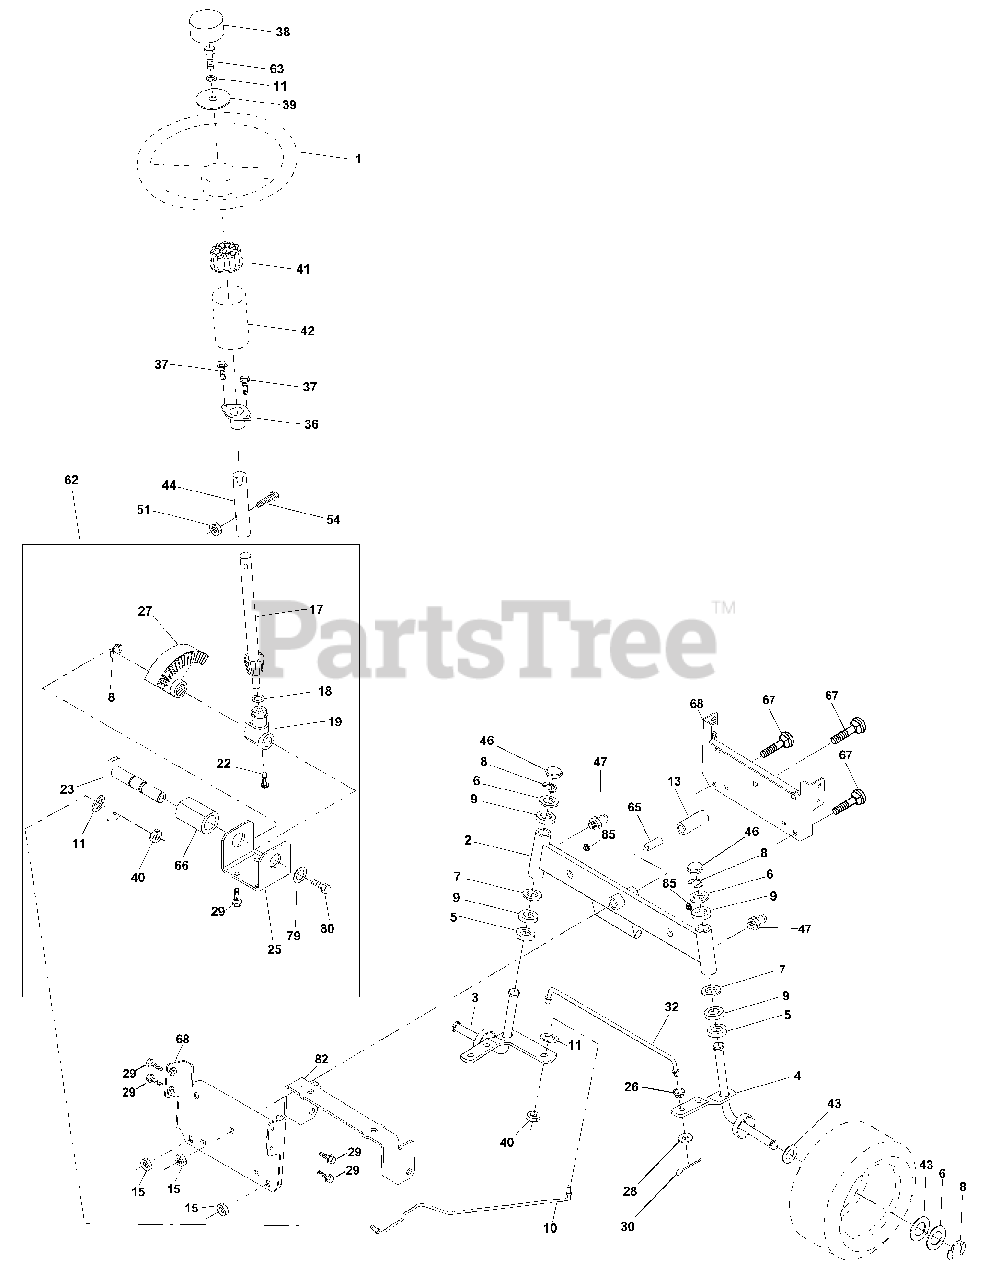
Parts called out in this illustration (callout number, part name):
1	Wheel Steering
2	Axle Asm Stmp Dropped STLT
3	Spindle Asm LH
4	Spindle Asm RH
5	Bearing Race Thrust Harden
6	Washer 25/32 X 1-5/8 X 16 Ga
7	Washer 27/32 X 1-1/4 X 16 Ga
8	Ring Klip #t5304-75
9	Bearing Col Strg Blk
10	Link Drag
11	Washer Lock Hvy Hlcl Spr 3/8
13	Spacer Brg. Axle Front
15	Nut Hex Flange Lock
17	Shaft Asm Strg
18	Washer Thrust 515 x 750 x 033
19	Support Shaft
22	Screw Hex Wsh Hd Torx
23	Shaft Asm Pittman
25	Bracket Steering
26	Bushing Link Drag
27	Gear Sector
28	Washer 13/32 x 7/8 x 16 Ga.
29	Screw 3/8-16 x .75
30	Pin Cotter 1/8 x 3/4 Cad.
32	Rod Tie
36	Bushing Strg
37	Screw
38	Insert Cap Strg Wh Au
39	Washer 13/32 X 2-3/8 X 12 Ga
40	Lock nut
41	Adaptor Wheel Strg
42	Boot Steering Dash
43	Washer 25/32 X 1 1/4 X 16 Ga
44	Extension Steering Shaft LR/LT
46	Cap Spindle Fr Top Blk
47	Fitting Grease
51	Nut Lock Hex w/Ins 5/16-18
54	Bolt Fin Hex 5/16-18 Unc x 1-1/4
62	Kit, Steering Assembly Svc
63	Bolt Fin Hex 3/8-16unc x 1 Gr. 5
65	Brace Axle
66	Bearing Arm Pittman
67	Bolt Rdhd Sq 3/8-16 Unc x 2-1/4
68	Axle, Brace
79	Washer 13/32 x 1-1/4 x 12 Ga.
80	Bolt Hex Nylon 3/8-16 x 3/4
82	Bracket Susp. Chassis Front
85	Fastener Christmas Tree
